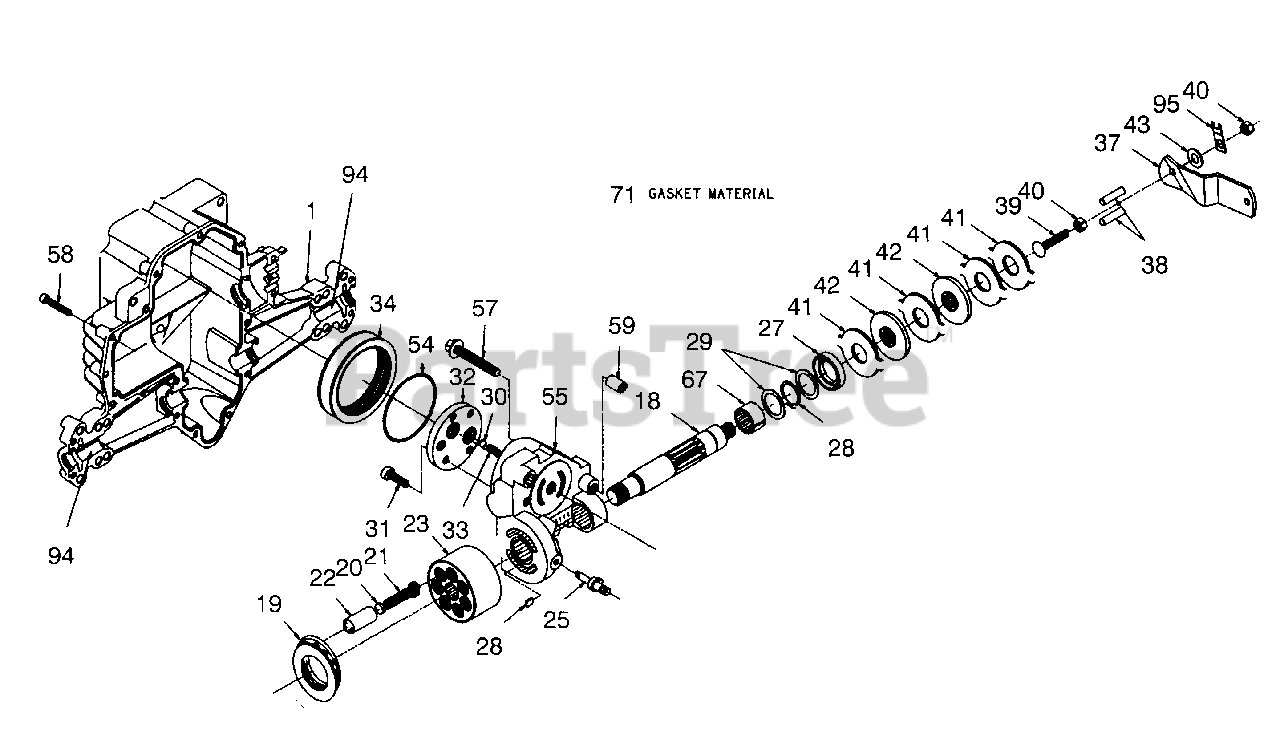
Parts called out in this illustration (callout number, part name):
1	Housing-Lower
18	Shaft-Motor
19	Bearing-Thrust
20	Seat-Piston Spring
21	Spring-Piston
22	Piston
23	Block-Cylinder (Motor)
25	Actuator-Bypass
26	Plate-Bypass
27	Seal-Lip
28	Ring-Retaining
29	Washer
30	Ball
31	Spring-Check Valve(Mod)
32	Plate-Check Valve
33	Socket Hd. Cap Screw
34	Oil Filter Element
37	Lever-Brake
38	Pin-Actuating
39	Bolt
40	Nut-Hex Lock
41	Stator-Brake
42	Rotor-Brake
54	O-Ring
55	Center-Section
57	Bolt
58	Bolt
59	Pin
67	Du Bearing
71	Gasket Material(1 oz.)
94	Grease Durina "O"(2.16 oz.)
95	Strap-Locking
